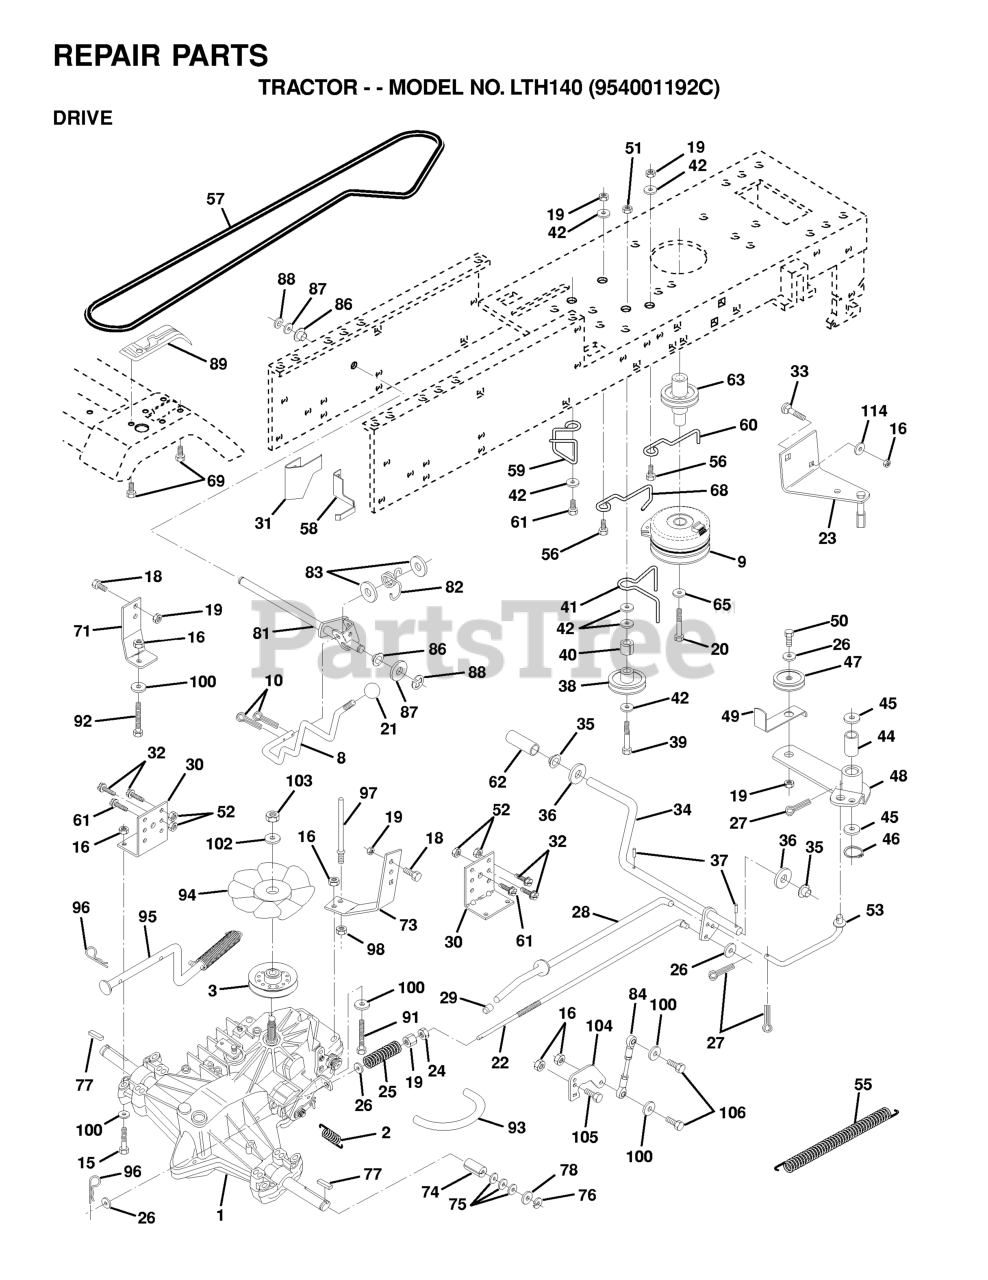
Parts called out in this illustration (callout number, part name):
1	TRANSAXLE ASMBLY
2	SPRING BRAKE
3	PULLEY, TRANSAXLE
9	CLUTCH.ELECT.EVX.
10	PIN COTTER
16	NUT.71038.31-18.HEX.NYLOCK
19	NUT
20	BOLT, CLUTCH
21	KNOB.DELUXE.(PISTOL.GRIP).BLAC
22	ROD BRAKE HYDRO
23	BRACKET, ASM CLUTCH MTG EVX
24	NUT
25	SPRING ROD LT
26	WASHER
27	COTTER PIN
28	ROD BRAKE PARK LT
29	PLUNGER CAP
30	BRACKET TRANSAXLE
31	KEEPER BELT LH
32	BOLT
33	RP BOLT 5/16-18 X3/4 ZN/YEL GR
34	SHAFT PEDAL FOOT
35	BEARING.NYLON
37	DRIVE PIN
38	PULLEY.IDLER.FLAT
41	BELT KEEPER LT NLA
42	WASHER
44	BEARING LT (2 2)
47	IDLER PULLEY
49	RETAIN BELT
50	BOLT
52	LOCKNUT
53	LINK, CLUTCH LT
55	SPRING, RETURN LT
57	DRIVE BELT, LTH & YTH TRACTORS
58	KEEPER BELT LH
59	KEEPER CENTER SPAN
60	KEEPER BELT ENGLH
61	SCREW
62	COVER, PEDAL (1 2)
63	PULLEY, CLUTCH ELECT EVX
65	LOCKWASHER
68	KEEPER,BLT ENG LT
69	SCREW.HI-LO.CONSOLE
71	STRAP LH TORQUE
73	STRAP RH TORQUE
74	SPACER SPLIT
77	SQUARE KEY
81	SHAFT ASSY
82	SPRING,TORSION
83	WASHER
84	ROD.TIE.BALL.4.75
86	BUSHING.STEERING.ROD LTB-WSL
89	CONSOLE HYDRO LT
91	BOLT.FIN HEX 5/16-18UNC X2 1/4
92	HEX BOLT
93	LINE FUEL HYD 4"
94	FAN 7" HYDRO
95	CONTROL ARM, BYPASS HYDRO
96	RETAINER M
97	KEEPER BELT RH
100	WASHER M
103	NUT.HEX.1/2-20
104	CONTROL ARM
106	BOLT.5/16-18X1-1/4 FULL.THREAD
114	Washer 11/32 x 3/4 x 14 Gauge
